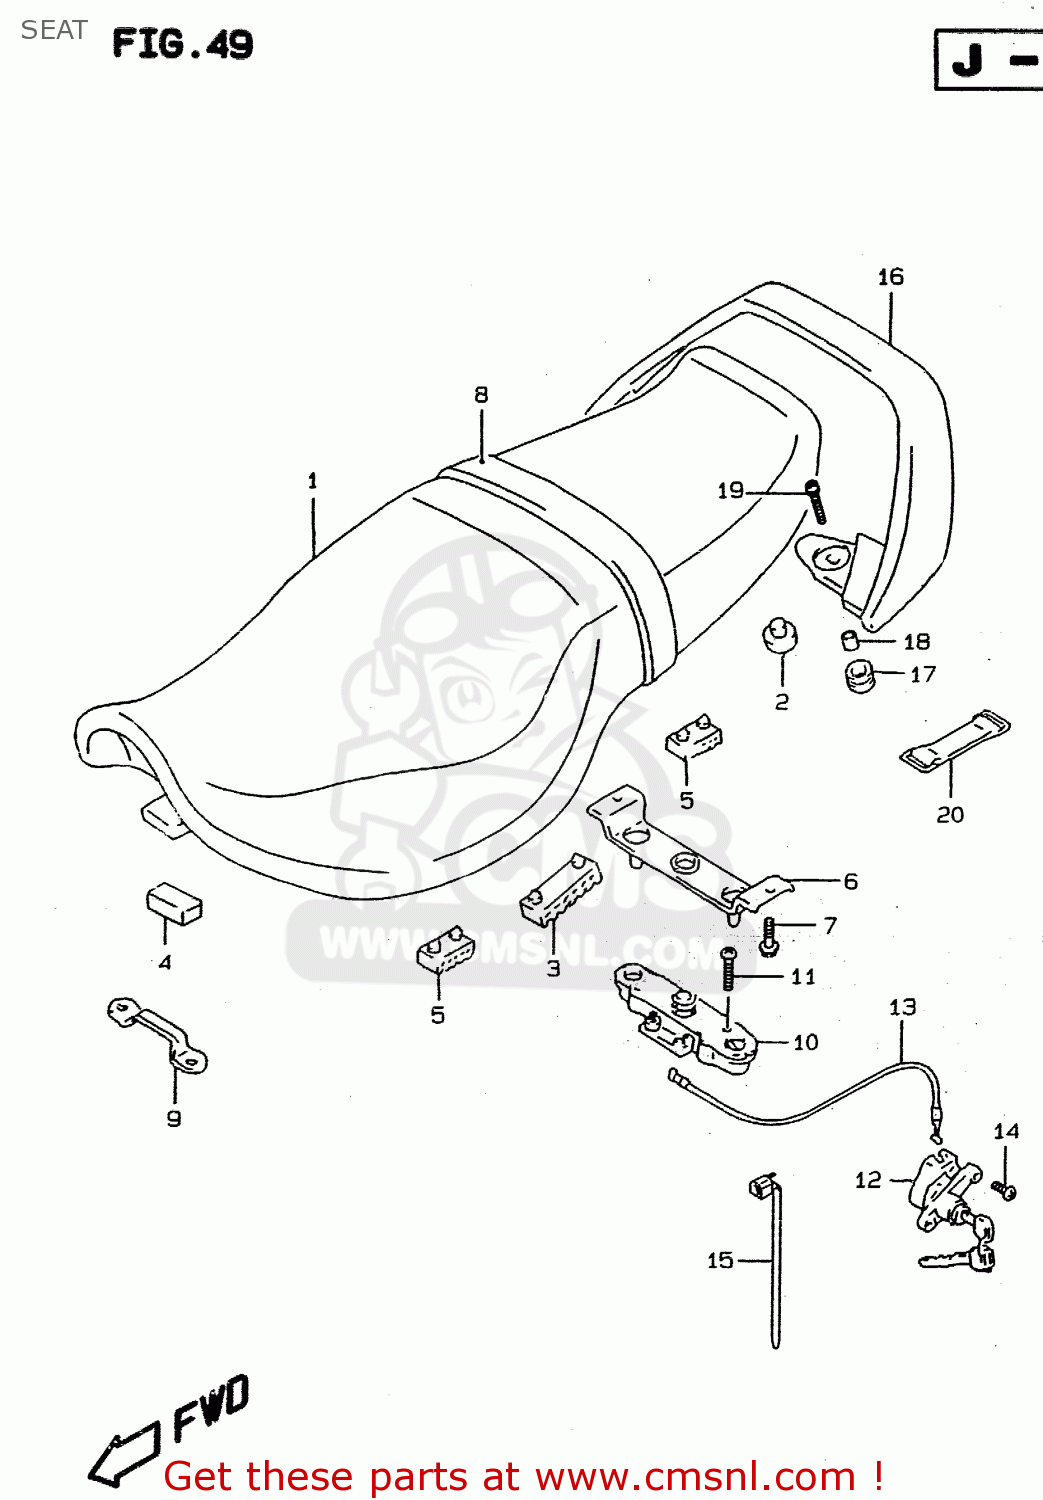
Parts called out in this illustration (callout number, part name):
1	SEAT ASSY
2	CUSHION
3	CUSHION,SEAT
4	CUSHION,FR(20X40X15)
5	CUSHION,SEAT(40X20X15)
6	STRIKER,SEAT LOCK
7	BOLT
8	BAND, SEAT (BLACK)
9	PLATE,SEAT FR HOOK
10	LOCK ASSY,SEAT STRIKER
11	SCREW 6X30
12	LOCK SET,SEAT
13	CABLE,SEAT LOCK
14	SCREW(6X12)
15	CLAMP L:165
16	HANDLE,PILLION RIDER
17	CUSHION
18	WASHER(8.5X28X1.6)
19	BOLT
20	BAND
